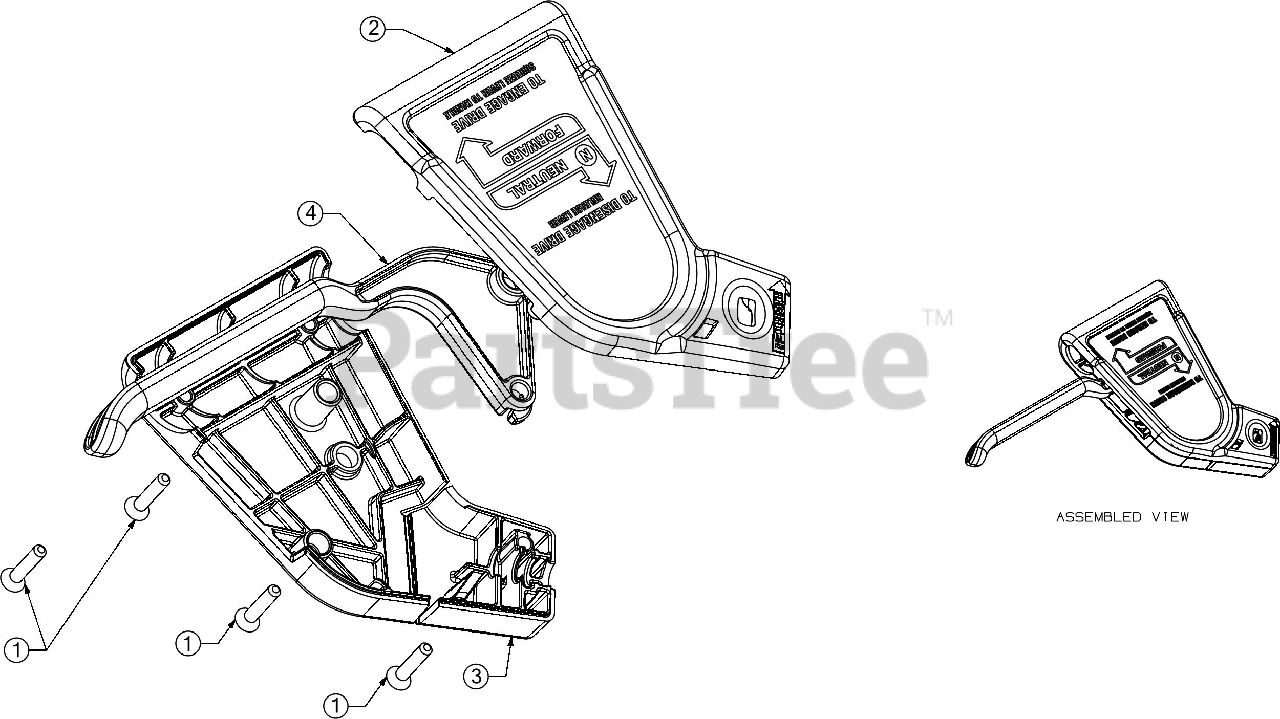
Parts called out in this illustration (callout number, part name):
1	SCREW #10-16 X 1.00
3	SQUEEZEBOX CONTROL COVER
4	SELF PROPELLED LEVER
